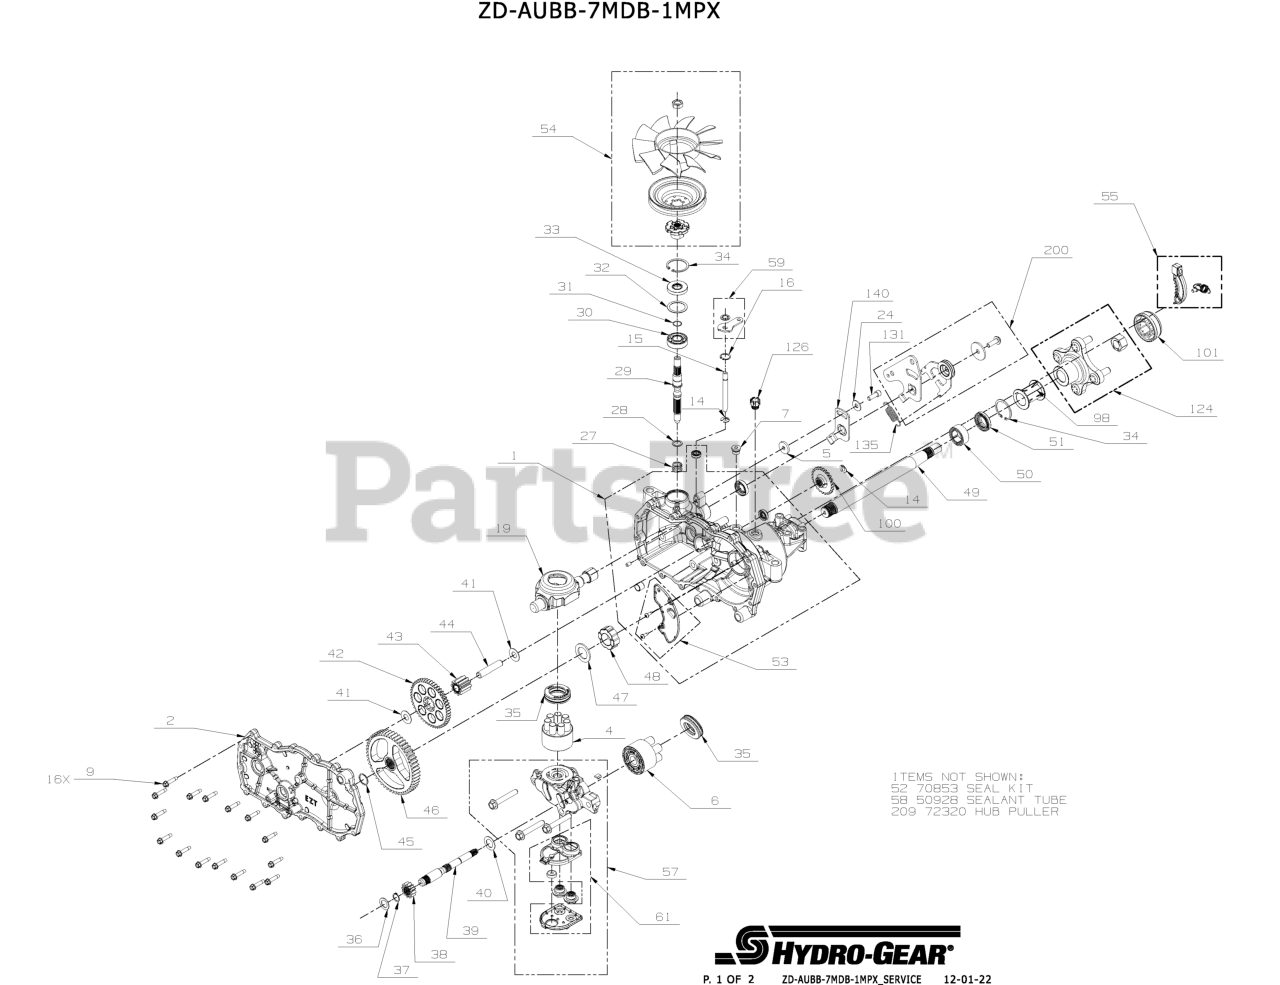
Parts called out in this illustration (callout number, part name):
1	ASSEMBLY, MAIN HOUSING
2	ASSEMBLY, SIDE HOUSING
4	ASSY, BLOCK 7 PISTON
6	KIT, 10 CC BLOCK
7	PLUG, STEEL (WITH SEAL)
9	SCREW,HEX WASHER 1/4-20X1.125
14	RING. RETAINING
15	ROD, BYPASS
16	RING, RET .750
19	TRUNNION, SWASHPLATE
27	SPRING. BLOCK
28	WASHER. THRUST .59 X .79 X .04
29	SHAFT, INPUT
30	BRG, BALL 17X40X12
31	RING, RET WIRE .561 ID
32	WASHER 1.23X1.56X.04
34	RING, RET 1.56 INT
35	BEARING. THRUST 30 X 52 X 13
36	WASHER, .63 X 1.00 X .05 FLAT
37	RETAINING RING, MOTOR SHAFT
39	SHAFT, MOTOR
40	WASHER .71 X 1.16 X .04
41	WASHER .5X1.0X.032
43	GEAR, 10T JACKSHAFT
44	PIN, JACKSHAFT
45	SPIRAL RETAINING RING
46	GEAR 52T BULL
48	INBOARD SLEEVE BEARING
49	SHAFT, AXLE
52	KIT, SEALS AND RETAINING
53	KIT, EXPANSION PLATE RH
54	KIT, FAN/PULLEY
55	KIT, BRAKE ARM
57	KIT-CENTER SECTION W/FILTER RH
58	SEALANT TUBE 10.1OZ.
59	KIT, BYPASS ARM
61	KIT, FILTER
100	DISC, COG BRAKE
124	KIT, HUB 4 BOLT
126	ASSEMBLY, FITTING 9/16-18 BREATHER
131	KIT, RTN SCREWS
135	SPRING, EXTENSION
140	ARM, NEUTRAL RIGHT
200	KIT, RTN BIDIRECTIONAL
209	HUB PULLER 5 BLT HYDGEAR 72320
